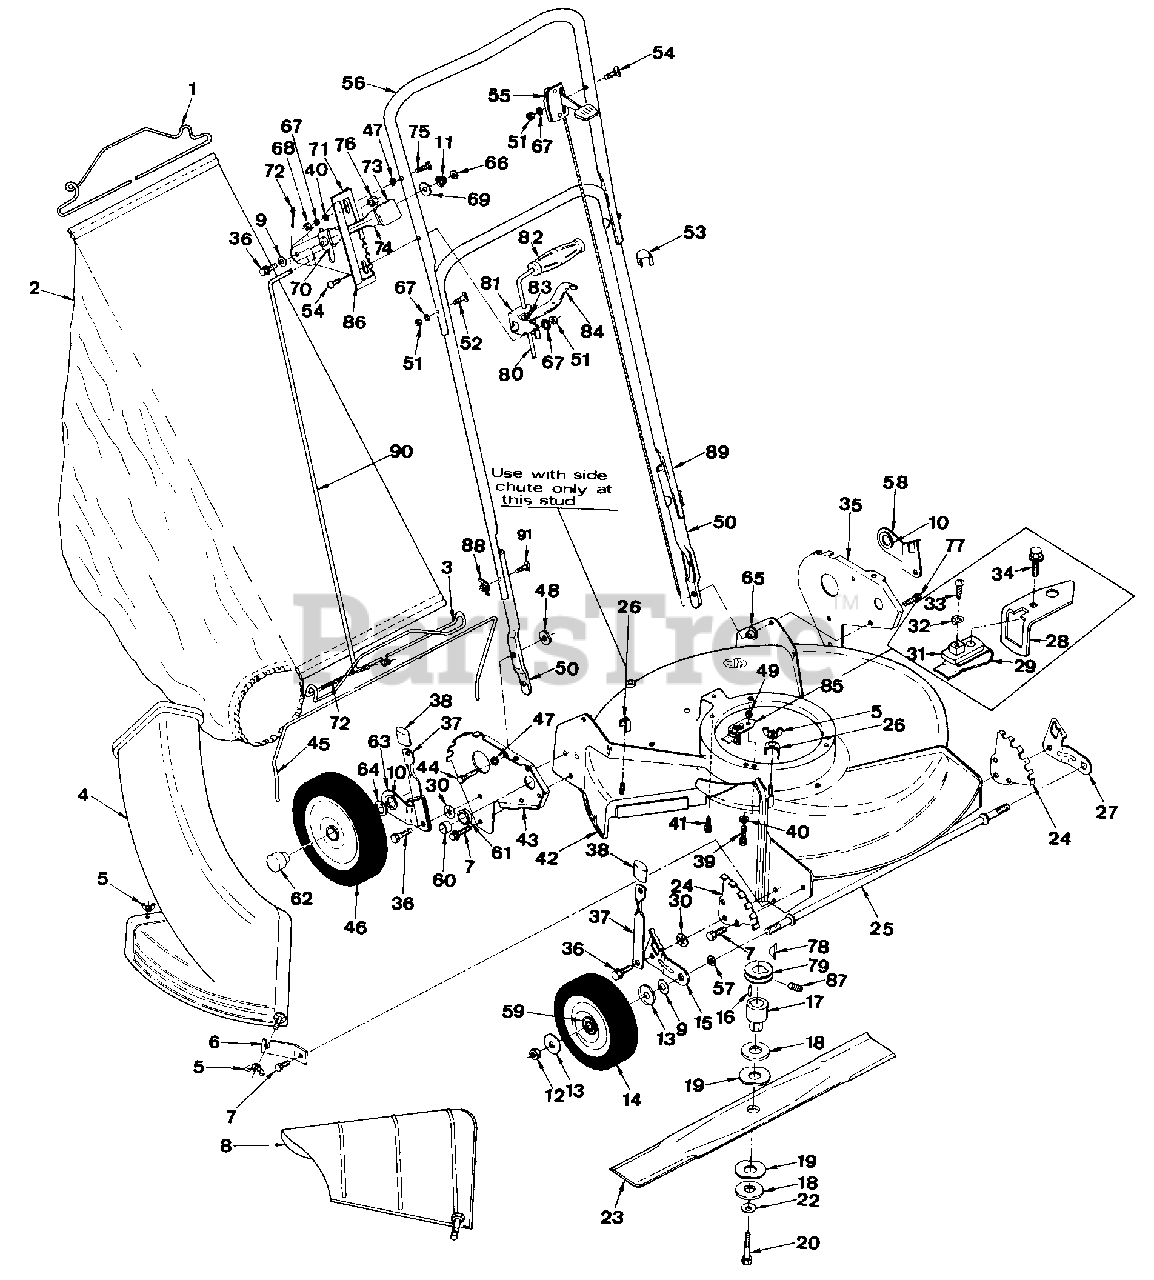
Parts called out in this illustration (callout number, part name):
1	Rear Wire
2	Grass Bag
3	Front Wire
4	Bag Chute Assembly
5	5/16-18 Wing Nut
6	Side Brkt.
7	5/16-18 x 5/8 SEMS
8	Side Chute Ass'y.
9	Spring Washer
10	Bearing
11	Shift Spring
12	7/16-20 Jam Lock Nut
13	Hub Cap, Front
14	Front Wheel, 7 x 1:50
15	Wheel Arm, Front RH
16	KEY, (#6) 5/32 x 5/8" Woodruff
17	Shock Clutch
18	Clutch Washer
19	Fiber Washer
20	Cap Screw, 3/8-24 x 2", Grade 5
22	Washer
23	Cutter Blade
24	Front Bracket
25	Axle
26	Clamp
27	Wheel Arm, Front.LH
28	Ground Strap
29	Interlock
30	Push Nut
31	Insulator
32	Tab Washer
33	10-18 x 3/4" Screw
34	10-24 x 5/8 SEMS CS
35	Rear Bracket, LH
36	5/16 Shoulder Screw
37	Height Latch
38	Grip
39	5/16-24 x 1 5/8" CS, Grade 5
40	5/16 SAE Flat Washer
41	3/8-16 x 1 Cap Screw ST
42	Deck Assembly
43	Rear Bracket, RH
44	5/16-24 x 5/8 HHCS
45	Roll Bar
46	Rear Wheel
47	5/16 Int.-Ext. Tooth L'washer
48	5/16-24 Weld Nut
49	5/16-24 Hex Lock Nut
50	Lower Handle Stat
51	1/4-28 Hex Nut
52	1/4-28 x 1 1/4" CH Bolts
54	1/4-28 x 1 1/2 CH Bolt
55	Throttle Control
56	Upper Handle
58	Wheel Arm, Rear LH
59	Bearing
60	Flex Bushing
61	Ball Bearing
62	Hub Cap, Plastic
63	Wheel Arm, Rear RH
64	3/4 Special Washer
65	5/16-18 Dot "T" Nut
66	3/8 SAE Washer
67	1/4 Int. Tooth L'Washer
68	1/4-20 Hex Nut
69	Friction Washer
70	Wear Block
71	Detent
72	1/8" x 3/4" Cotter Pin
73	Shift Knob
74	Shift Handle
75	1/4-20 x 1 1/4 Carriage Bolt
76	5/16-18 Jam Nut
77	5/16-18 x 3/4 HHWFCS ST
78	Hi-Pro Key
79	Engine Pulley
80	Release Rod
81	Release Brkt.
83	Spring
84	Release Latch
85	Interlock Ass'y.
86	Shift Decal
87	1/4-20 x 5/16 Skt. Set Screw
88	Wing Nut
89	Lower Handle Pivoting
90	Shift Rod
91	1/4-28 x 1 3/4 Curved Head Bolt
